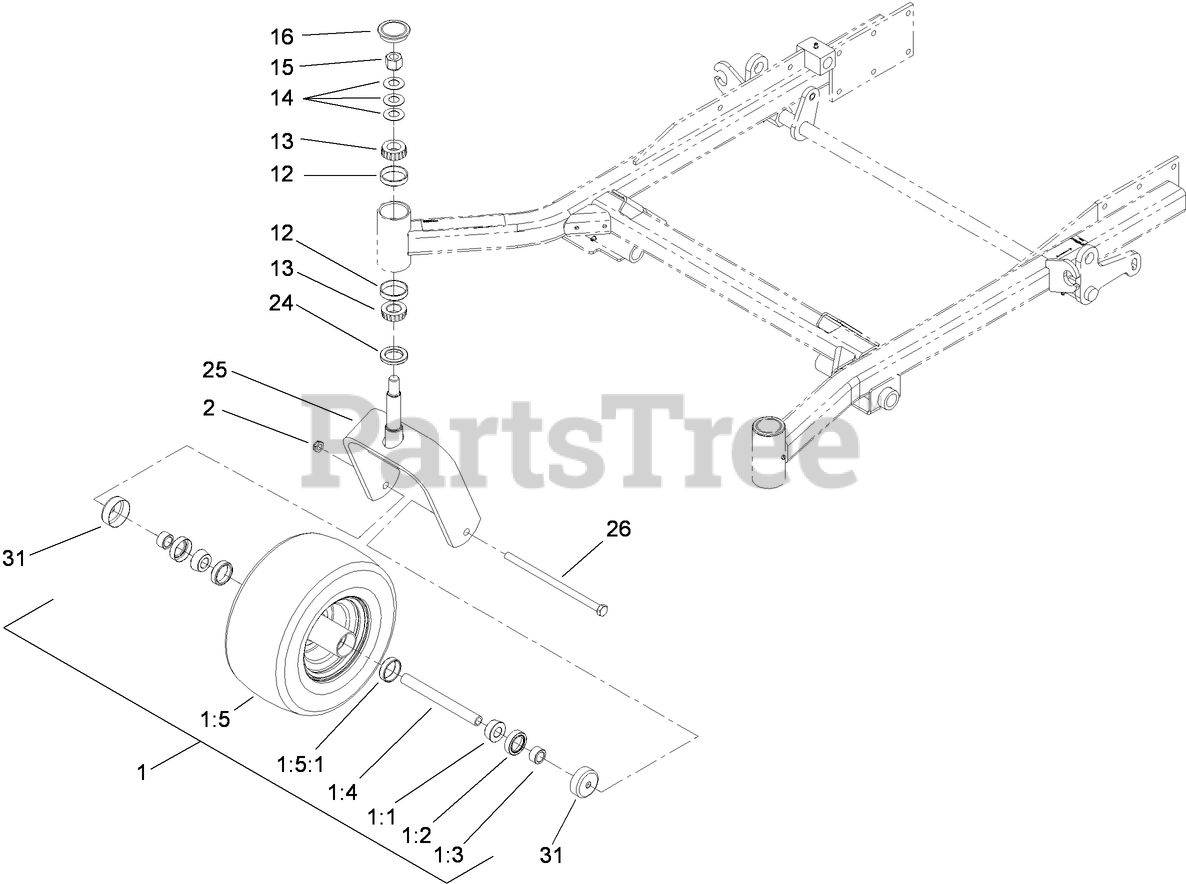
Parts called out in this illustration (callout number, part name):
1	WHEEL AND TIRE ASM
1:1	BEARING-CONE, TAPER
1:2	SEAL-CASTER
1:3	SPACER-NUT
1:4	AXLE-CASTER
1:5	WHEEL AND TIRE ASM
1:5:1	BEARING-CUP
2	NUT-LOCK, NI
12	BEARING-CUP, TAPERED
13	BEARING-CONE, TAPERED
14	WASHER-BELLVILLE
15	NUT-LOCK, NI
16	CAP-GREASE
24	SEAL-GREASE
25	CASTER-FORK
26	Screw-HH
31	GUARD-SEAL
